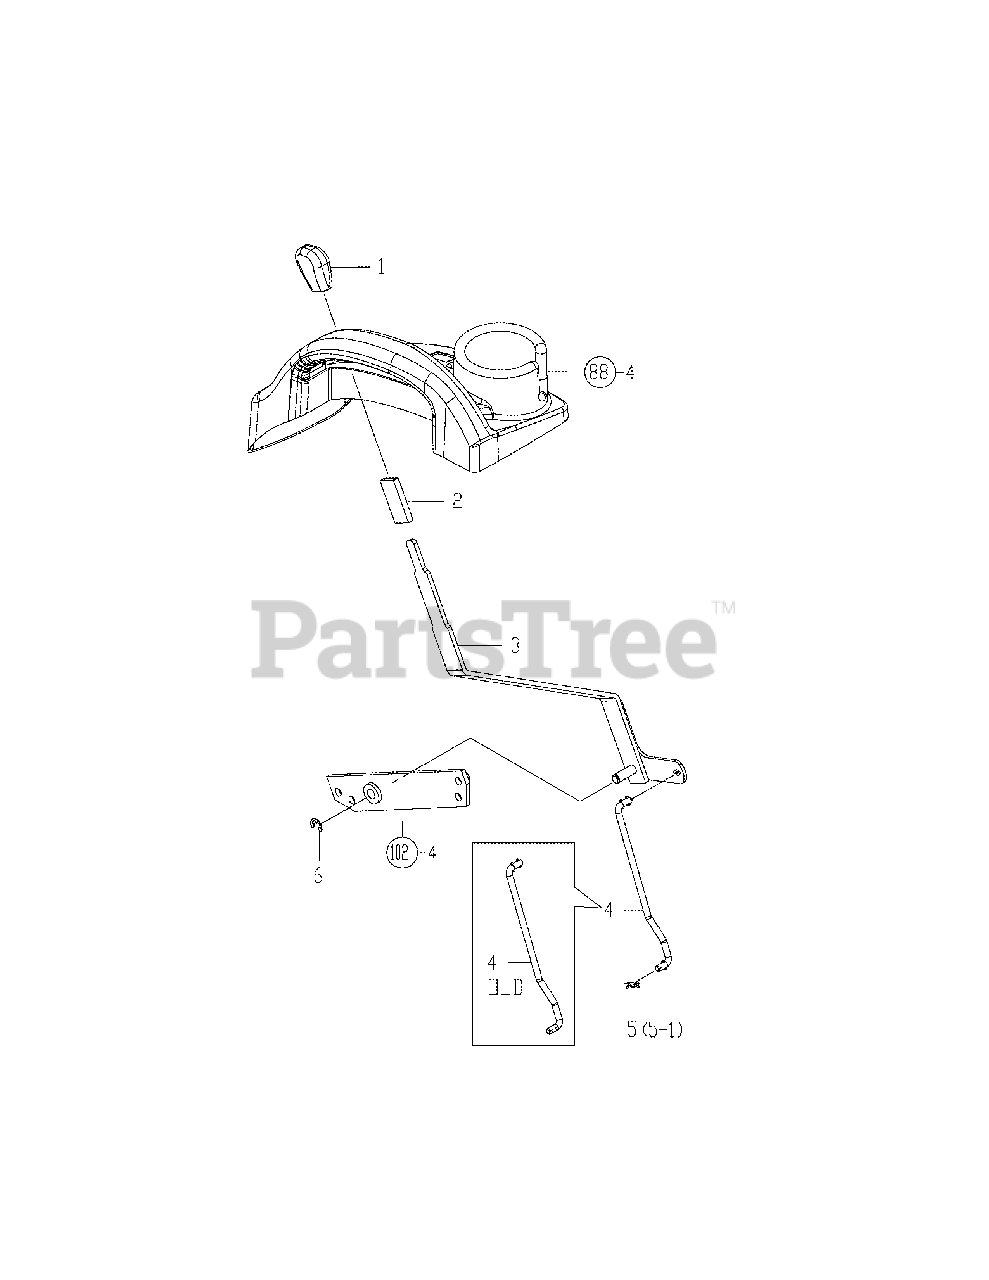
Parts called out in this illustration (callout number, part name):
2	Tube, Protective
3	Lever Cmp, Pto
5-1	Pin, Snap
